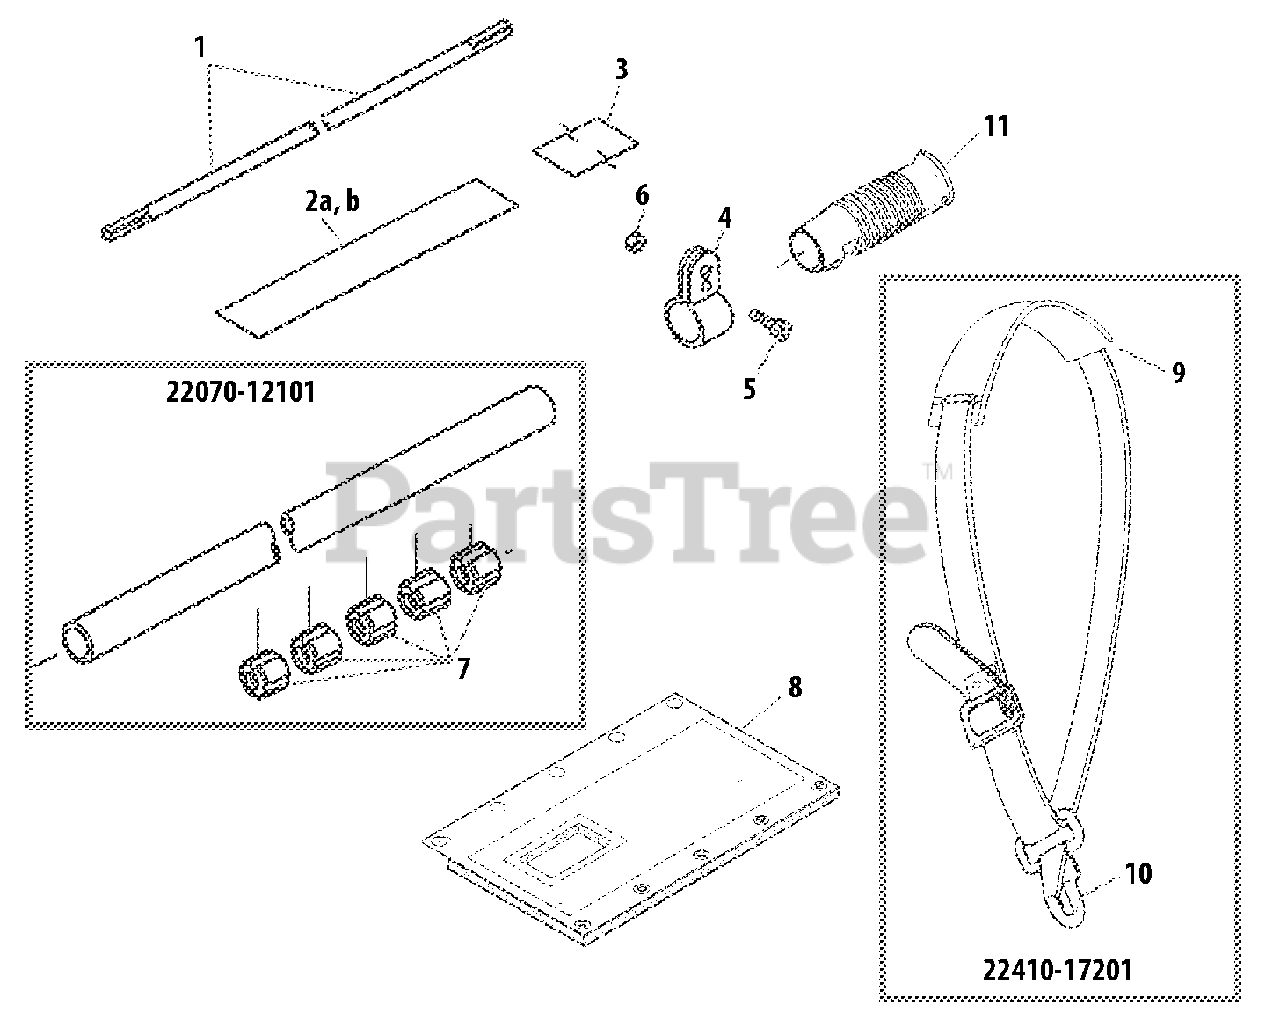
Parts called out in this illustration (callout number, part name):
1	MAINSHAFT
2	LABEL - MODEL
3	LABEL, CAUTION
4	HANGER
5	BOLT 5×12
6	NUT M5
7	BUSHING
8	CUSHION, MAIN PIPE
9	PROTECTOR
10	HOOK, SNAP
11	GRIP, REAR
22070-12101	MAIN PIPE ASSY
22410-17201	STRAP ASSY
